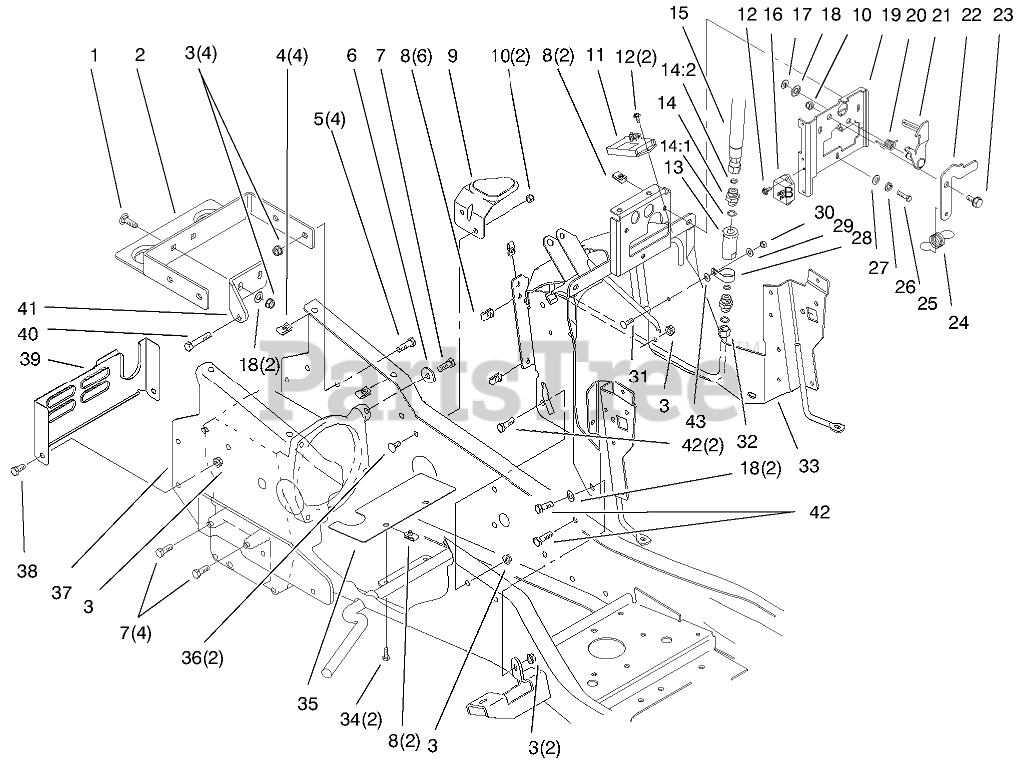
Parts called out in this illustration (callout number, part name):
1	BOLT-CARR
2	Support-Gas Tank
3	NUT-LOCK, NI
4	NUT-U
5	SCREW-HH
6	WASHER
7	SCREW-HH, LOCK
9	SUPPORT-TANK, FUEL
10	NUT-LOCK, NI
11	MODULE - KAWASAKI
12	SCREW
13	FILTER-SCREEN, HYD
14	FITTING-HYD. STRAIGHT
14:1	O-RING
14:2	O-RING
15	HOSE ASM
16	MODULE - CRUISE
17	RING-RETAINING
18	WASHER-FLAT
19	BRACKET-LATCH
20	SPRING-LEVER, LATCH
21	LEVER-LATCH
22	LATCH-LEVER, TENSION
23	BOLT-SHOULDER
24	SPRING-LEVER, LATCH
25	SCREW-HH
26	WASHER-LOCK
27	WASHER-FLAT
28	CLAMP-R
29	WASHER-FLAT
30	NUT-LOCK, NI
31	BOLT-CARR
32	TUBE-HYD
33	WA-TOWER
34	SCREW-HH
35	BAFFLE-FAN
36	BOLT-CARR
37	Frame
38	SCREW-HH
39	COVER-REAR
40	SCREW-HH W/LOCTITE
41	Strap-Torque
42	SCREW-HH
43	PUSHNUT-RETAINER, BOLT
